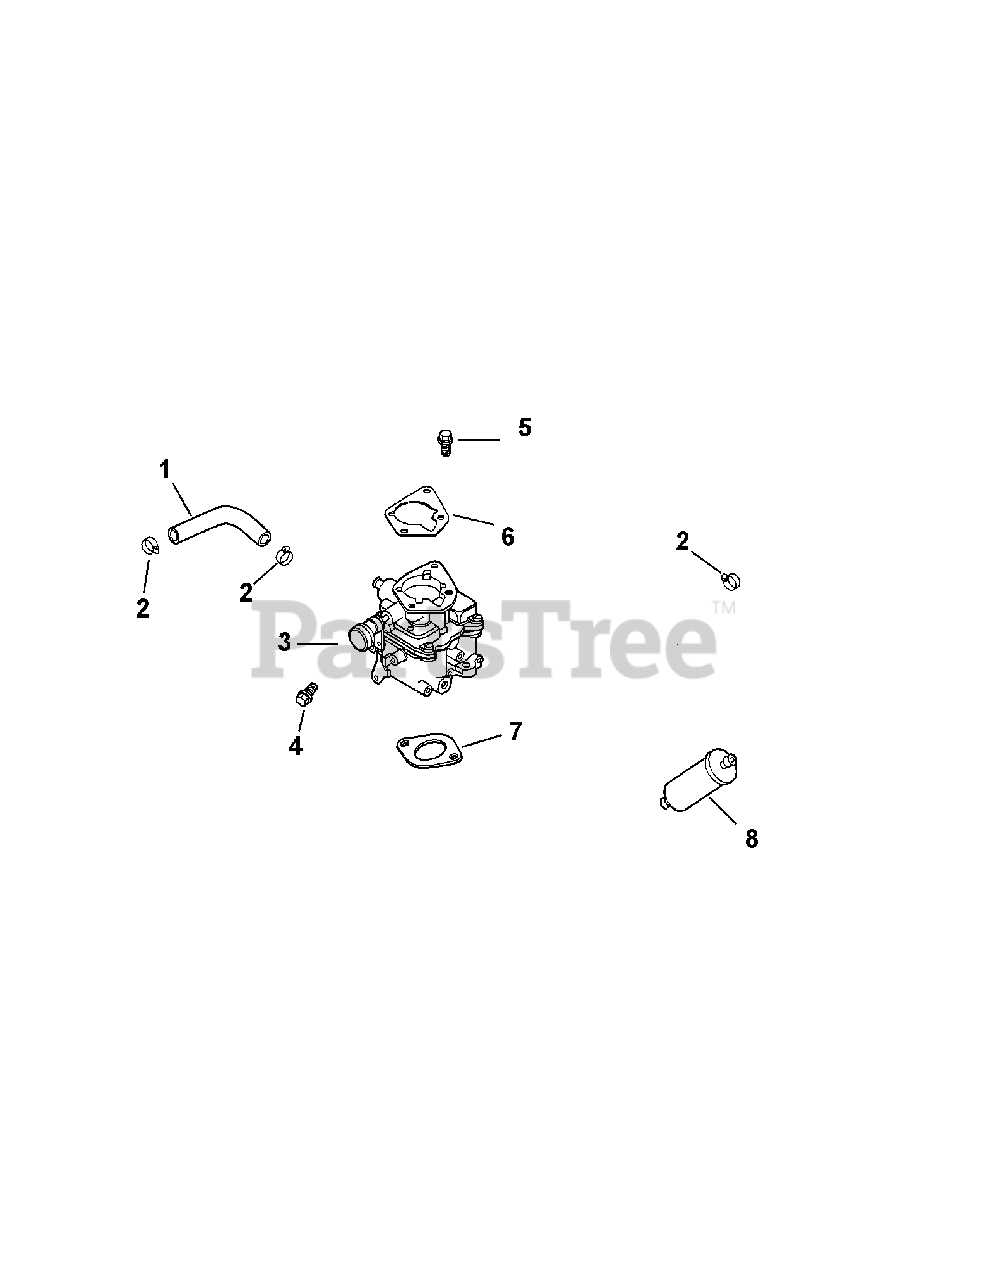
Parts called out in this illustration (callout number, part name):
1	Hose,Lw Perm.Fuel 24.00"
2	Clamp, Hose (Km)
3	Kit, Carburetor
5	Screw, Flg M6X1.0X25
6	Gasket, Air Cleaner Base
7	Gasket, Carburetor
8	Fuel Filter
